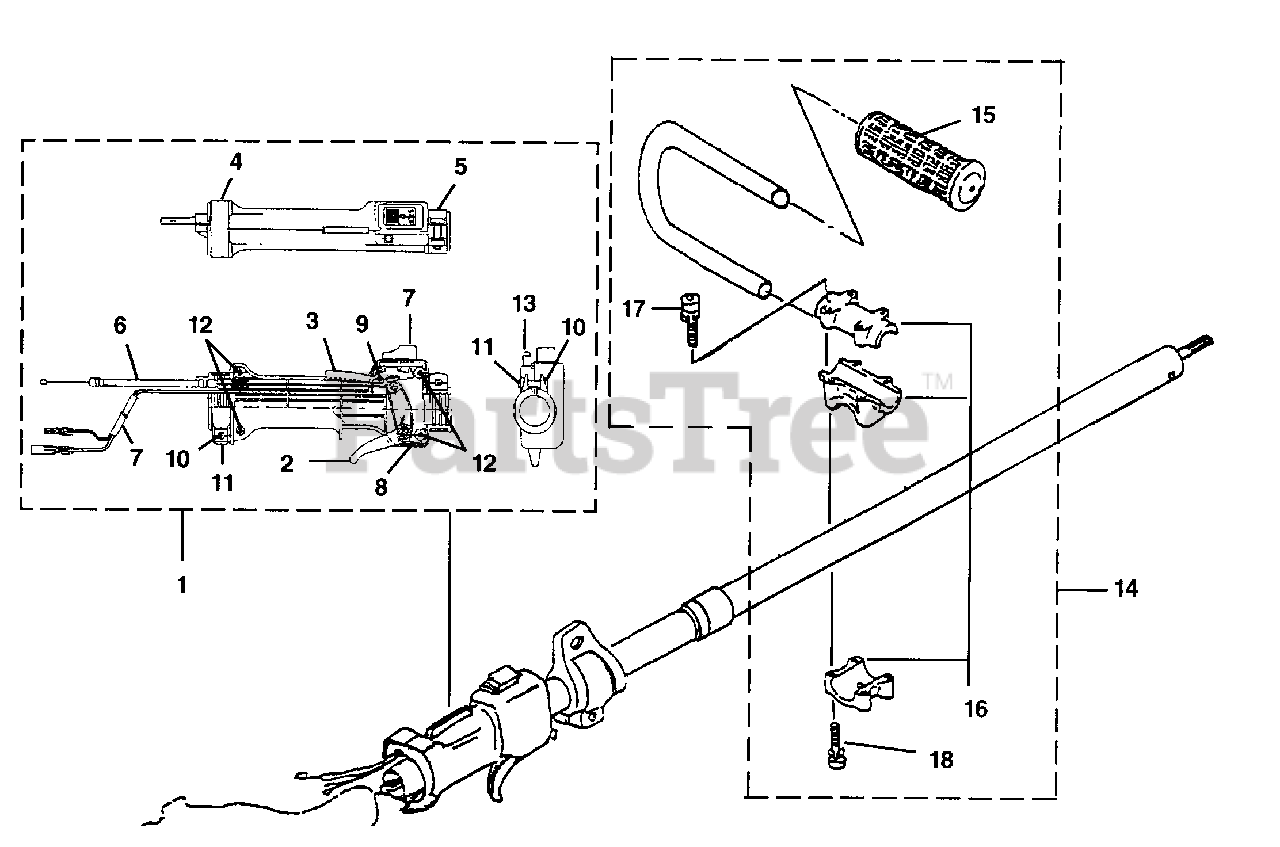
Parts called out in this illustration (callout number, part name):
1	CONTROL LEVER ASSEMBLY
2	THROTTLE - Trigger
3	LATCH - Trigger
6	CABLE - Throttle
7	SWITCH ASSEMBLY
12	SCREW - Tapping
13	LOCK - Throttle Start
14	HANDLE ASSEMBLY
16	HANDLE - Bracket Assembly
17	BOLT - Socket Hd (M5 x 25 SW)
18	BOLT - Socket Hd (M5 x 25 SW)
